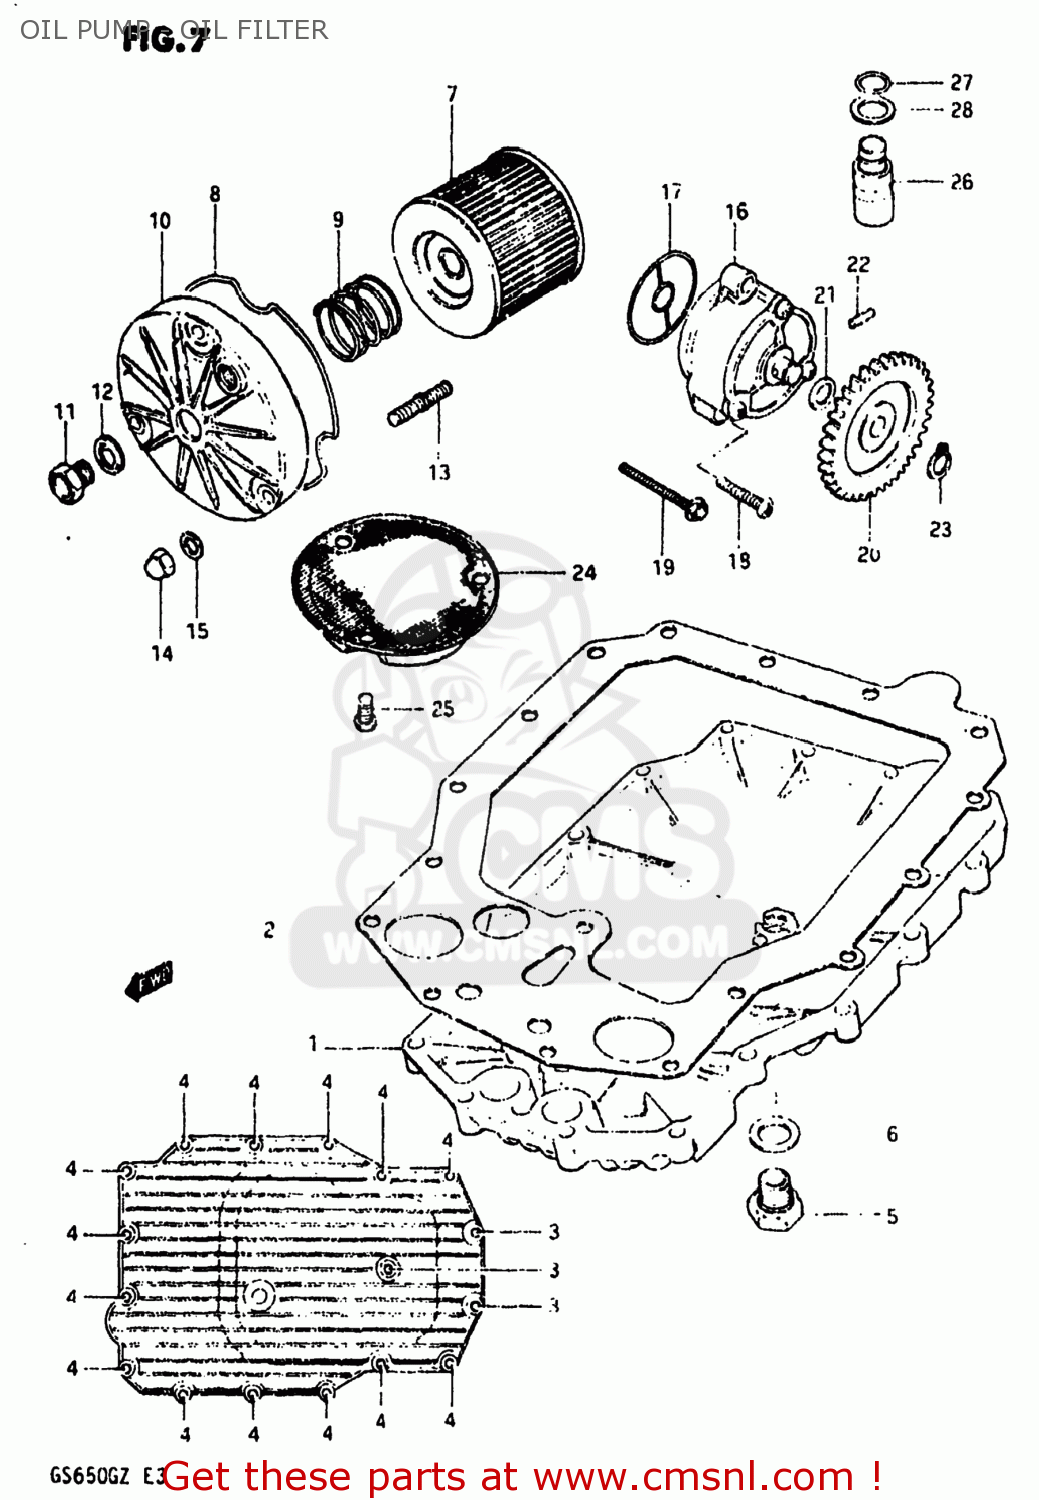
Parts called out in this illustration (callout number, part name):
1	PAN,OIL
2	GASKET,OIL PAN (MCA)
3	BOLT
4	BOLT
5	PLUG
6	GASKET(14X19.2X2) (NAS)
7	FILTER ASSY,ENGINE OIL
8	O RING,OIL FILTER CHAMBER CAP
9	SPRING
10	CAP,OIL FILTER
11	PLUG
12	GASKET(14X19.2X2) (NAS)
13	STUD 6X20
14	NUT
15	WASHER
16	PUMP ASSEMBLY,OIL
17	O-RING,OIL PUMP
18	SCREW
19	BOLT
20	GEAR,OIL PUMP DRIVEN
21	SHIM
22	PIN(4X15.8)
23	CIRCLIP
24	STRAINER,ENGINE OIL
25	SCREW 6X12
26	REGULATOR ASSEMBLY,ENGINE
27	O-RING
28	WASHER
